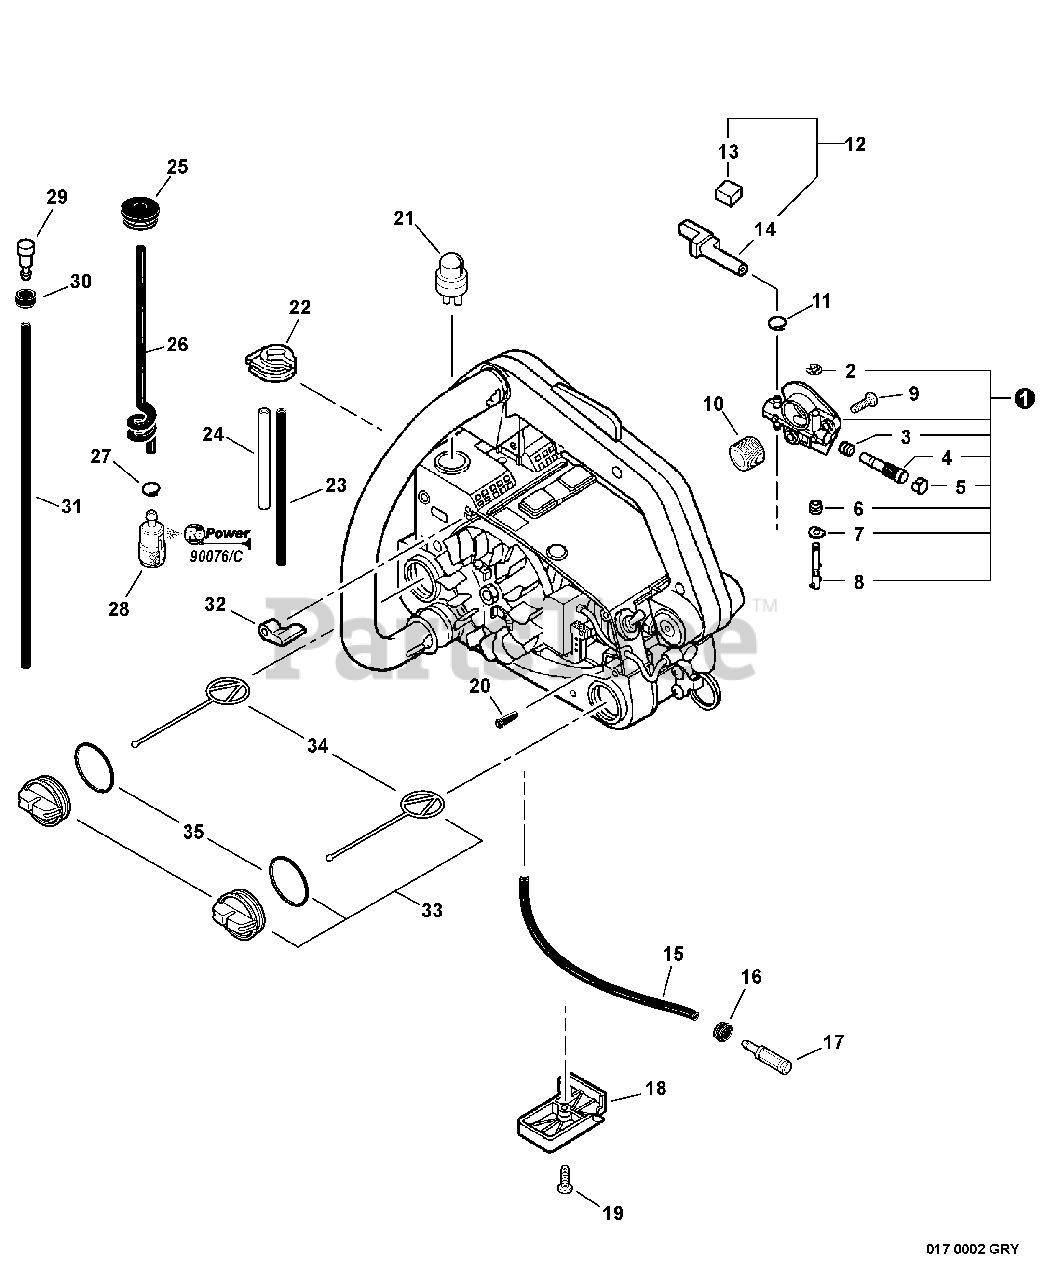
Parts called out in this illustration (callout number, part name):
1	AUTO-OILER ASSY
2	RING, RETAINING
3	SPRING, PLUNGER
4	PLUNGER ASSY
5	CAP, OIL PUMP
8	NEEDLE, ADJUST
9	SCREW - 5X12
10	GEAR - WORM
11	CLIP - 6.5
12	OIL PIPE KIT
13	PAD, FOAM
14	PIPE - OIL
15	PIPE - 3X6X115 -- BLACK
16	GROMMET
17	FILTER, OIL
18	COVER, BOTTOM - GRAY
19	SCREW - 4X16
20	VENT, TANK
21	PUMP, PURGE
23	PIPE - 3X5X70 -- BLACK
24	PIPE - 2X4X42 -- CLEAR
25	GROMMET
26	PIPE, FUEL - SPIRAL
27	CLIP - 6.5
28	FILTER, FUEL
29	VENT, FUEL TANK
30	HOLDER, VENT
31	PIPE - 3X5X150 -- BLACK
33	CAP ASSY - ORANGE
34	CONNECTOR, CAP
35	O-RING - 25
36	RePower TUNE-UP KIT
